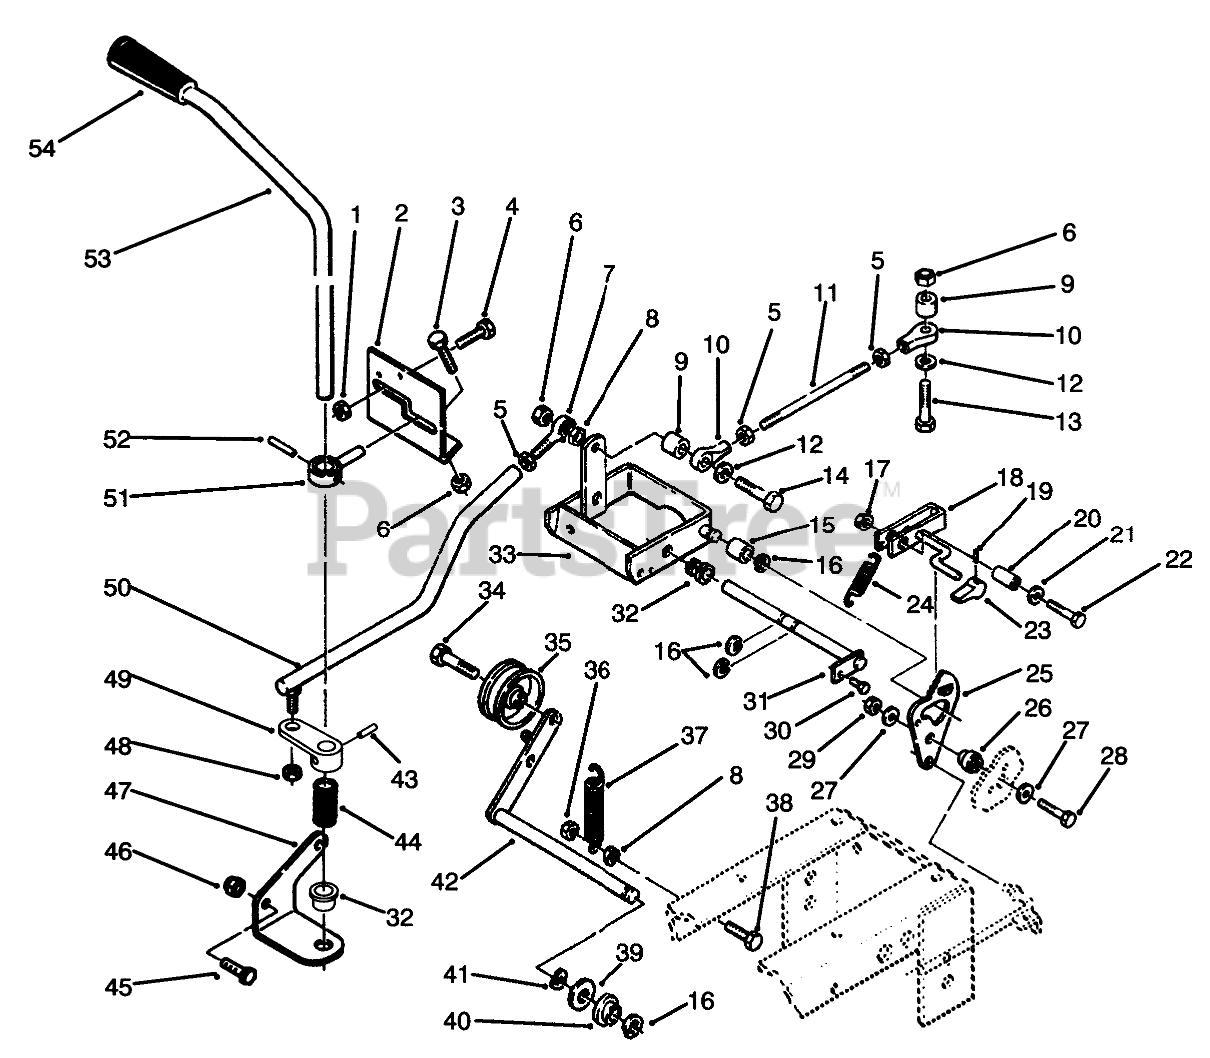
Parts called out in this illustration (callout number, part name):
1	NUT-LOCK, NI
2	BRKT-CONTROL
3	SCREW-HH
4	SCREW-HH
5	NUT-JAM
6	NUT-LOCK, NI
7	ROD END, 1/4-28
8	NUT-HEX
9	Spacer
10	ASSY ROD END
11	ROD-CONTROL
12	WASHER-FLAT
13	SCREW-HH
15	BEARING-CAM RETURN
16	RING-RETAINING, EXTERNAL
17	LOCKNUT-FLANGE
18	Lever-Parking Brake
19	PIN-SPIROL 3/32X5/8
20	SPACER
21	Washer
22	SCREW-HH
23	KNOB-PARKING BRAKE
24	EXTENSION-SPRING
25	Cam Plate
26	Spacer
27	WASHER-FLAT
28	SCREW-HH
29	NUT-LOCK, NI
30	SCREW
31	ASSY-ROD CAM PIVOT
32	NYLINER BUSHING
33	Cam Comtrol
34	SCREW-HH
35	PULLEY-IDLER
36	NUT-LOCK
37	SPRING-EXTENSION
38	SCREW-HH
39	Washer
40	BUSHING-FLANGED
41	CURVED-SPRING WASHER
42	WLDMT-IDLER ARM
43	PIN-SPECIAL
44	SPRING-COMPRESSION
45	SCREW-HH
46	NUT-LOCK, NI
47	Bracket-Control
48	NUT-LOCK
49	ARM-CONTROL
50	ASSY-ROD & BALL JOINT
51	GUIDE-CONTROL
52	SPIROL PIN 7/32X7/8
53	ROD-MOTION CONTROL
54	Knob-Motion Control
